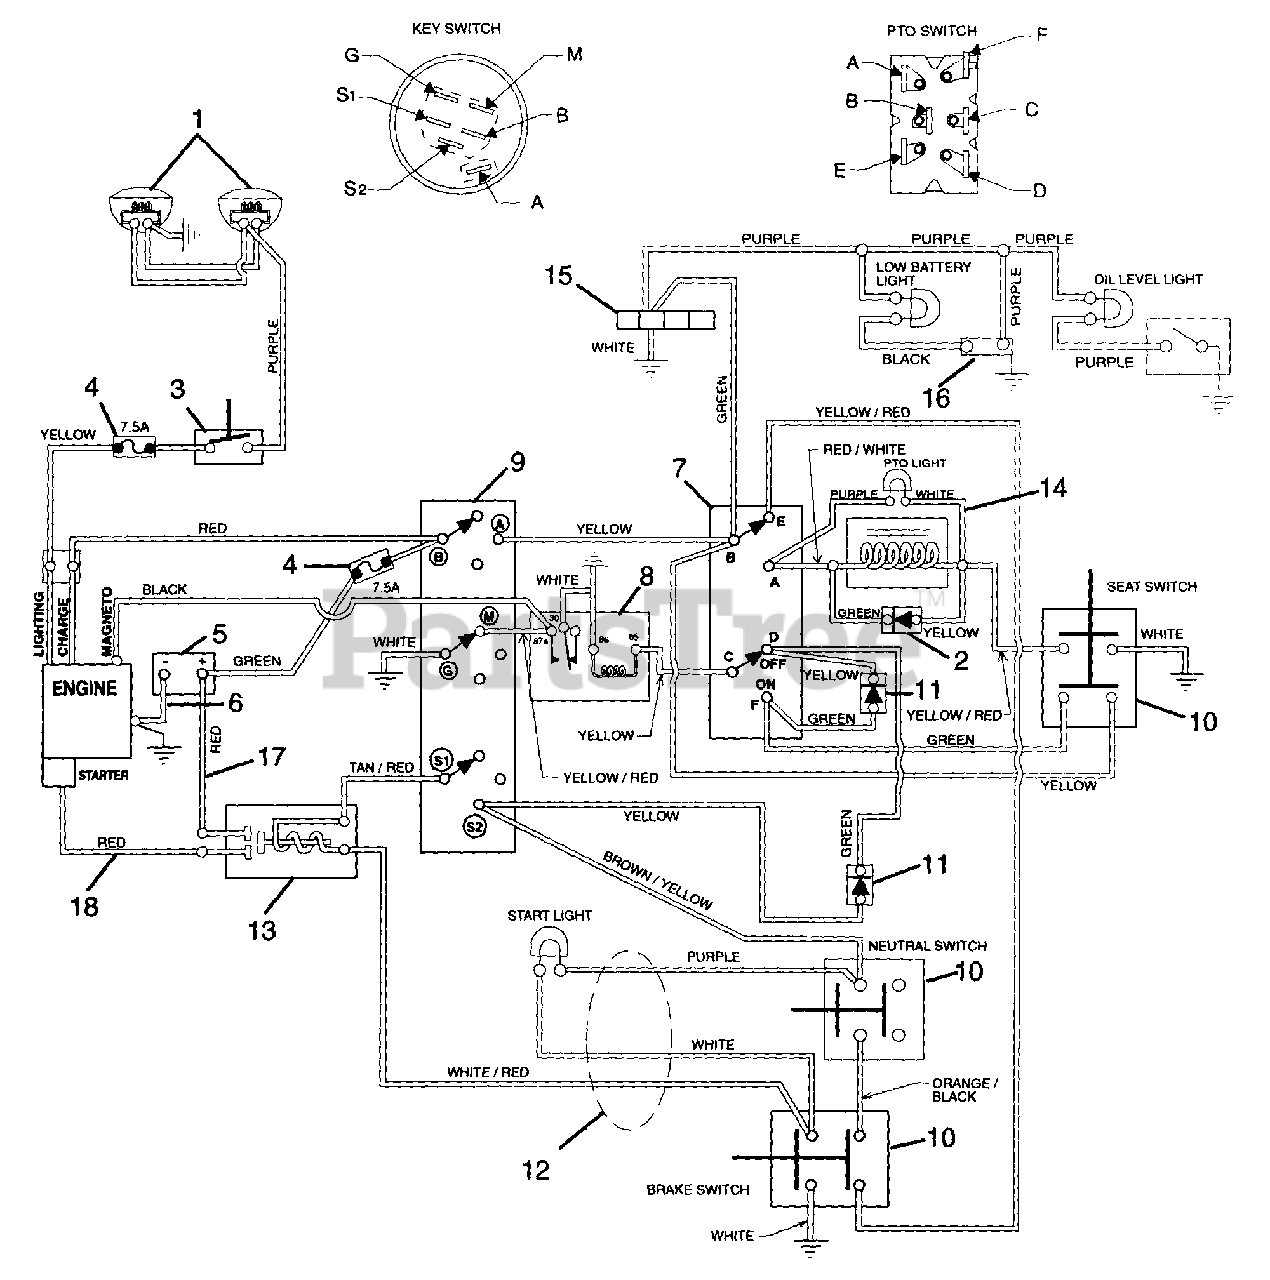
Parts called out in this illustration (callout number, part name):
1	HEADLIGHT- L.H.
2	DIODE & HOUSING
3	LIGHT SWITCH
4	7.5 Amp Fuse
5	BATTERY W/TUBE
6	GROUND CABLE .31X22.00X.31
7	SWITCH ASSEMBLY- PTO
8	RELAY
9	KEY SWITCH
10	SWITCH- DOUBLE POLE N.O./N.O.
11	MOLDED DIODE PLUG 1 AMP
12	WIRE HARNESS- YT13H
13	SOLENOID
14	ELECTRIC CLUTCH/BRAKE(1.8AMP)
15	HOUR METER W/ LEADS
16	VOLTAGE SENSOR
17	START CABLE 22"
18	STARTER CABLE 6.75"
